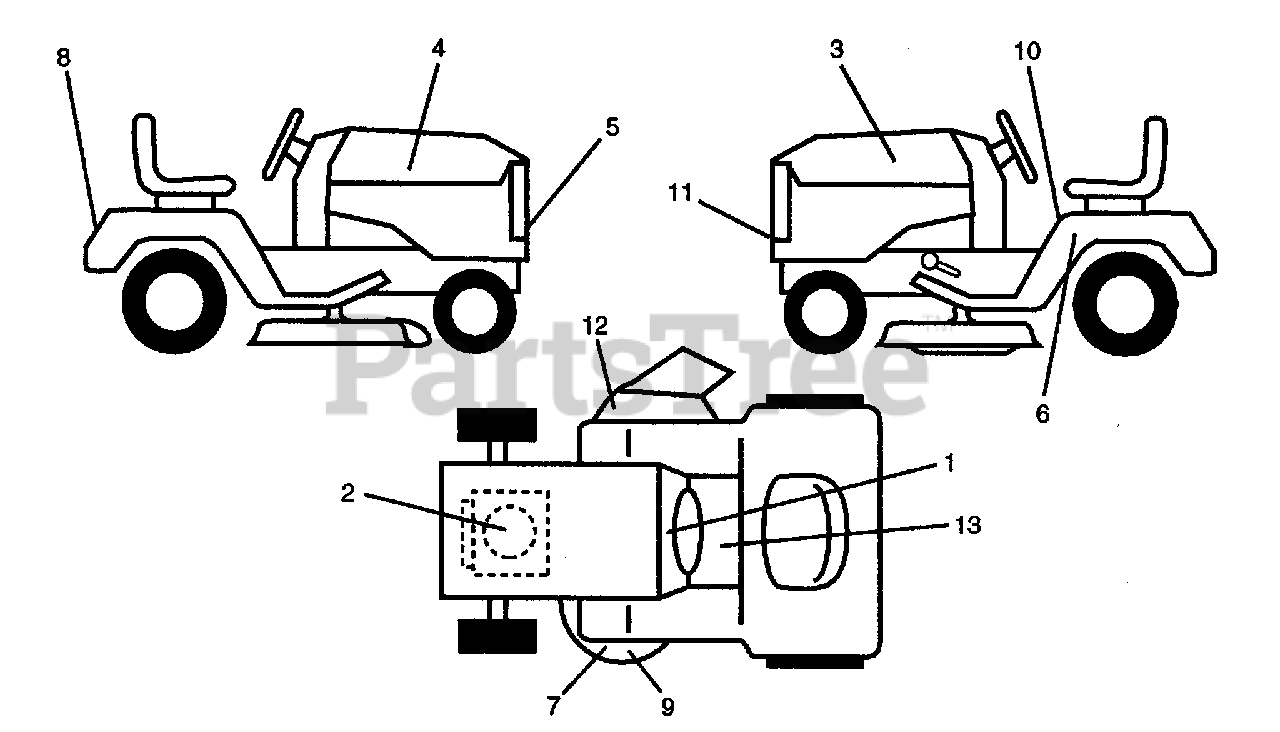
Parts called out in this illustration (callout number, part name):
1	Decal, Instruction, Engine (AYP part number)
2	Decal, Engine, HP (AYP part number)
3	Decal, Stripe, Hood, LH (AYP part number)
4	Decal, Stripe, Hood, RH (AYP part number)
5	Decal, Lightbox, Lower (AYP part number)
6	Decal, Height Indicator, Deck (AYP part number)
7	Decal, Rotating Blades (AYP part number)
8	Decal, Fender (AYP part number)
9	Decal, Enviro Deck (AYP part number)
10	Decal, Caution (AYP part number)
11	Decal, Grill
12	Decal, Danger (AYP part number)
13	Pad, Footrest (AYP part number)
